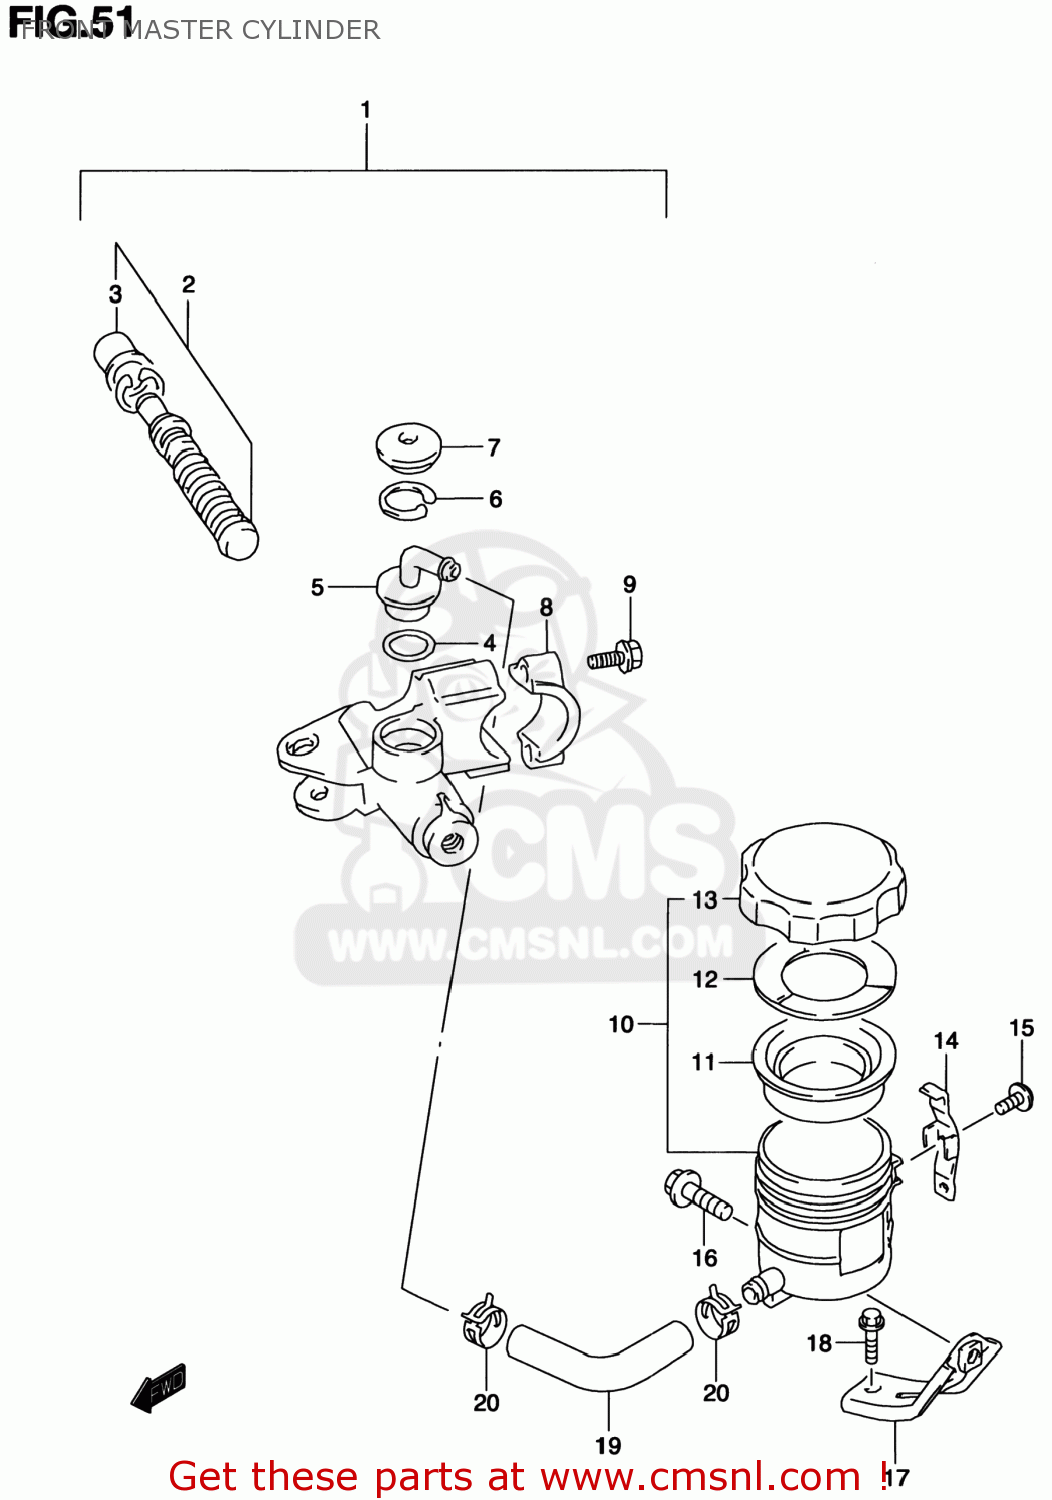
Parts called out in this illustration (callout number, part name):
1	CYLINDER ASSY,FR MASTER
2	PISTON & CUP SET
3	BOOT
4	O RING
5	CONNECTOR
6	CIRCLIP
7	COVER,DUST
8	HOLDER
9	BOLT(6X25)
10	TANK ASSY,RESERVOIR
11	DIAPHRAGM
12	PLATE,DIAPHRAGM
13	CAP
14	PLATE,RESERVOIR TANK CAP
15	SCREW
16	BOLT
17	BRACKET,RESERVOIR TANK FR
18	BOLT
19	HOSE,FR RESERVOIR TANK
20	CLAMP,RESERVOIR TANK FR
